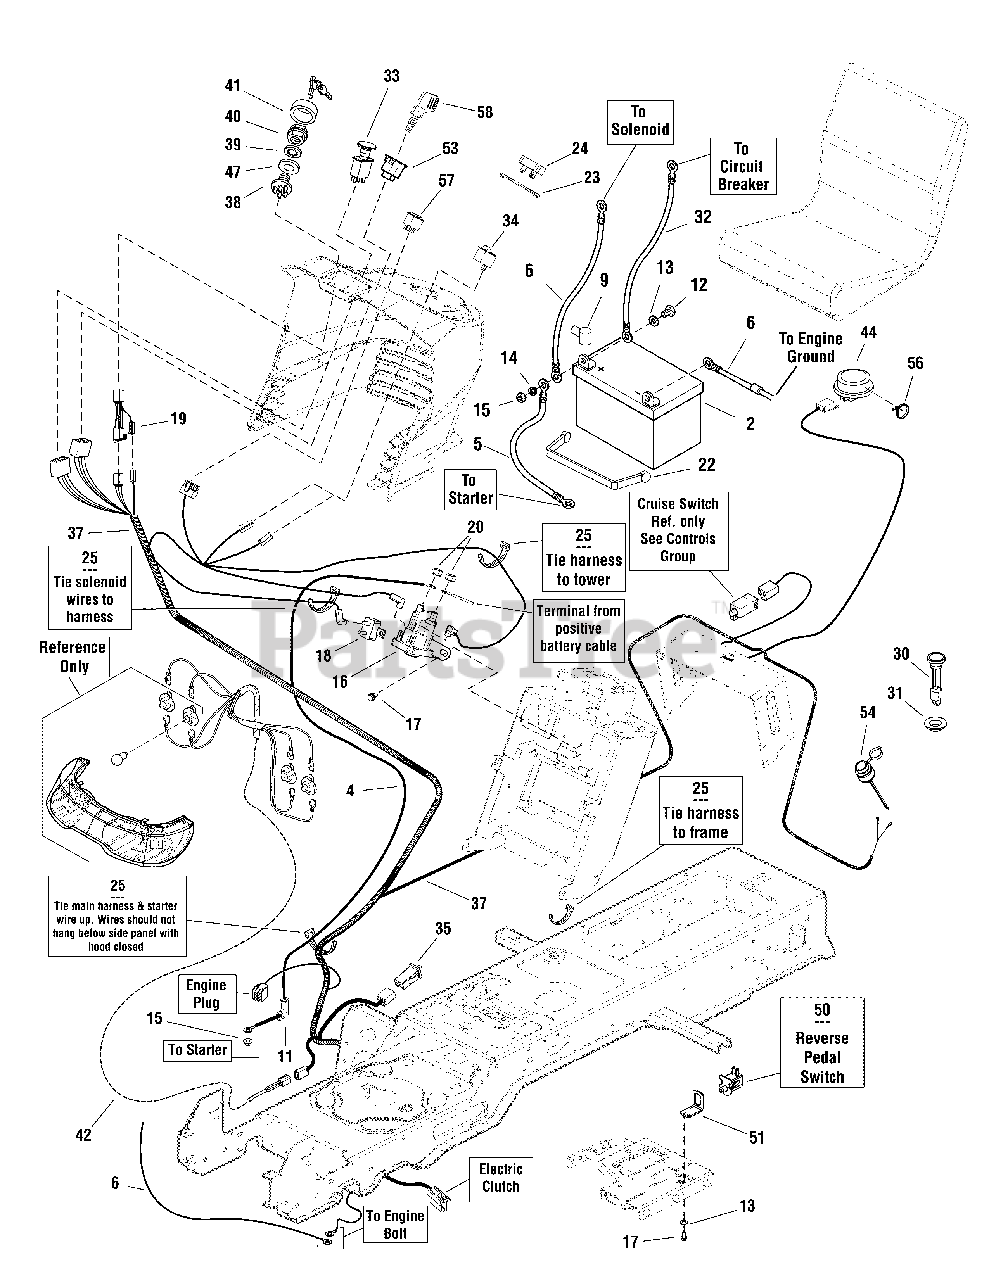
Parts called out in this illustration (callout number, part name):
2	BATTERY, 12 Volt
4	CABLE, #6 x 8" Lg
5	CABLE, #6 x 25" Lg
6	CABLE, #6 x 26" Lg
9	BOOT, Insulator Cable Terminal, Red
12	CAPSCREW, Hex Head, 1/4-20 x 3/4
13	WASHER, 1/4
14	LOCKWASHER, 1/4
15	NUT, Hex, 1/4-20
17	CAPSCREW, Hex Washer Head Taptite, 1/4-20 x 1/2, Black
18	BREAKER, Circuit, 12 Volt 20 Amps
19	HARNESS, Jumper
20	NUT, Hex KEPS Locking, 5/16-24
22	STRAP, Battery
25	TIE, Strap, 7-5/16 Long
30	GAUGE, Fuel
32	WIRE, 12GA 5-15/16 Long, Red
33	SWITCH, PTO Push/Pull Symbols
34	SWITCH, Headlights, 2 Terminal
35	SWITCH, Push Button, Foot Pedal
37	HARNESS, Main
38	SWITCH, Ignition
39	LOCKWASHER, Internal Tooth, 5/8, Thin
40	NUT, Flange, 5/8-32
41	COVER, For Ignition Switch, Plastic
42	HARNESS, Headlight
44	SWITCH, Seat
47	WASHER, Shim
50	SWITCH, Push Button
51	BRACKET, Switch Mount
53	SWITCH, RMO Module Only
54	OUTLET, 12 Volt
56	TIE, Self Locking,
57	SWITCH, Electric Lift Rocky
58	KEY, RMO Module, Plastic
